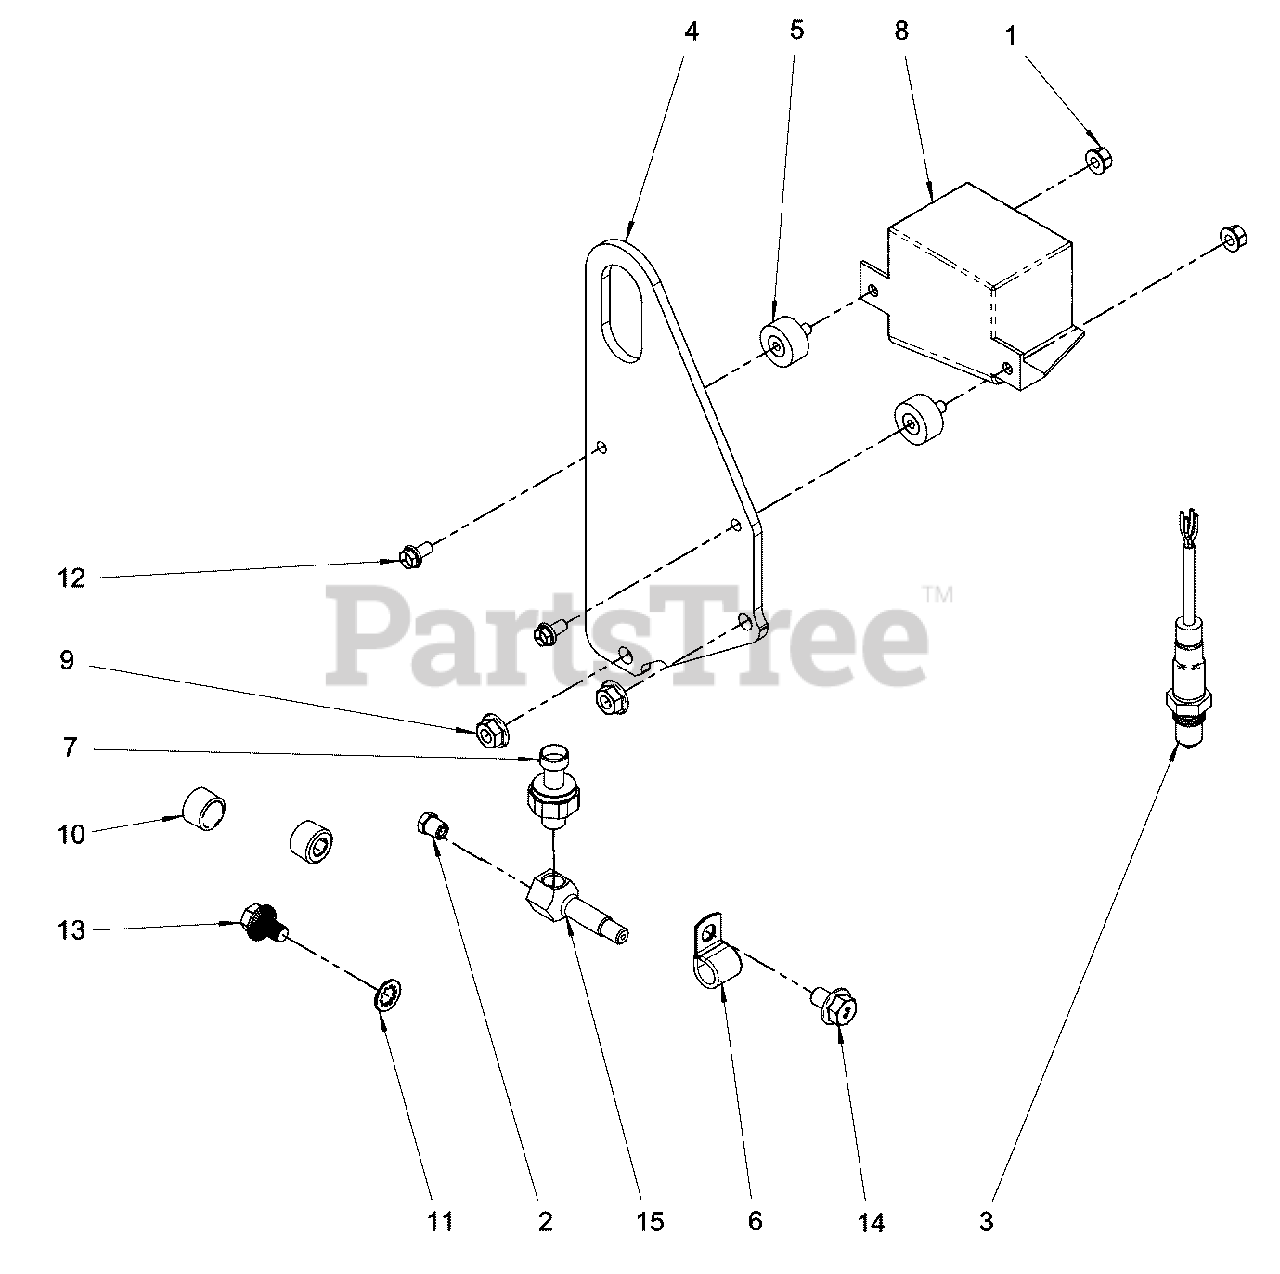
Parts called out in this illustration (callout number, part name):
1	* NUT
2	* PLUG
4	* BRACKET
5	ISOLATOR RELAY BOX
6	* CLAMP
7	OIL PRESSURE SENSOR
8	MAIN ENGINE HARNESS
9	* NUT
10	* PLUG
11	* WASHER
12	* BOLT
13	* BOLT
14	* BOLT
15	* FITTING
